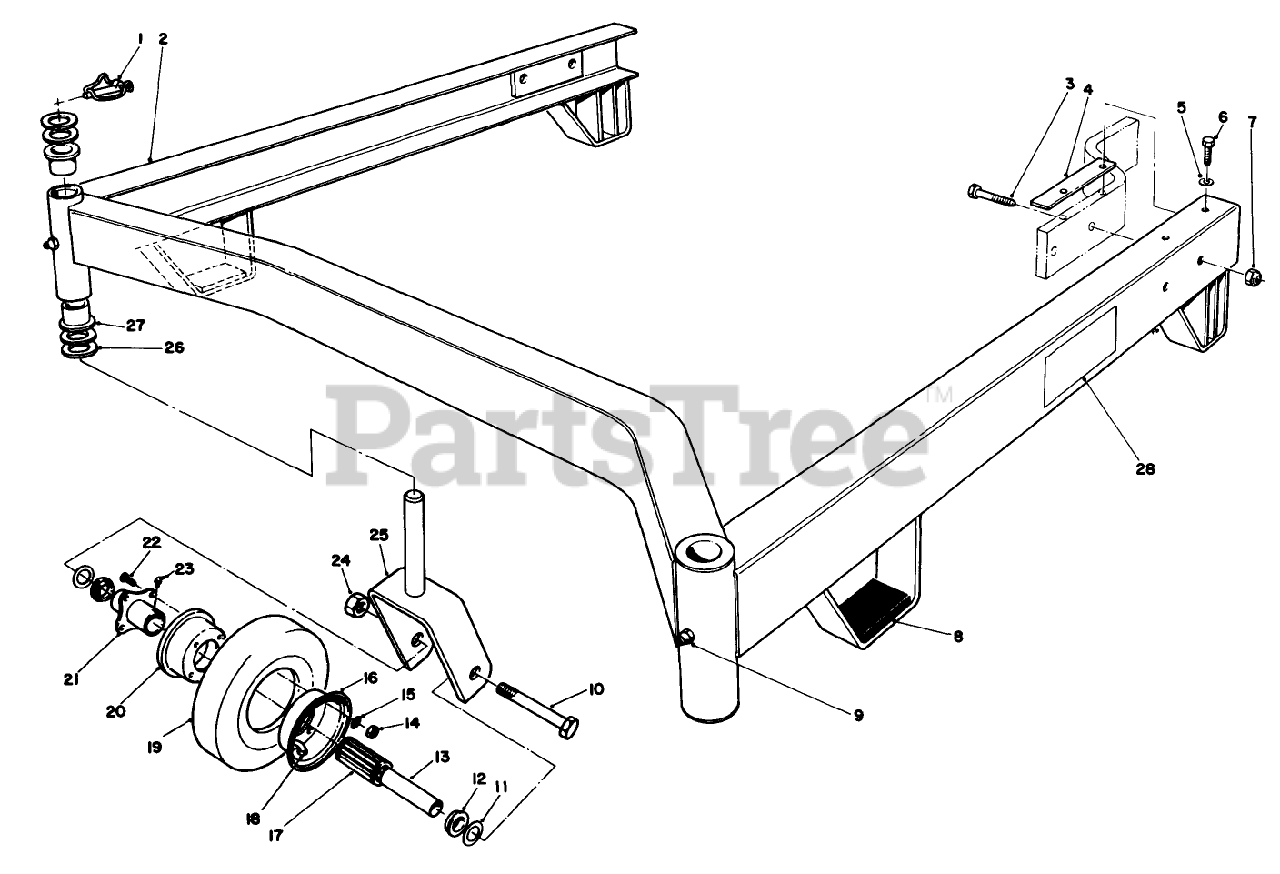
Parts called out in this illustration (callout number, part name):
1	PIN-LYNCH
2	52" Suspension Assembly (Incl. Ref. #9, 26 & 27)
3	SCREW-HH
4	SHIM-CARRIER
5	WASHER-FLAT
6	SCREW W/PATCH
7	NUT-LOCK, CONE
8	Pad-Rubber
9	FITTING-GREASE
10	SCREW-HH
11	SPACER-WHEEL
12	RETAINER
13	Bushing-Spanner
14	NUT-HEX
15	WASHER-LOCK
16	WHEEL HALF-MALE
17	BEARING-ROLLER
19	TIRE-8 Inch (4-PLY)
20	WHEEL HALF-FEMALE
21	HUB-CENTERED
22	WHEEL BOLT
23	FITTING-GREASE
24	NUT-LOCK
25	FORK-Castor
26	WASHER-THRUST
27	Bushing
28	DECAL-HOC, LH
